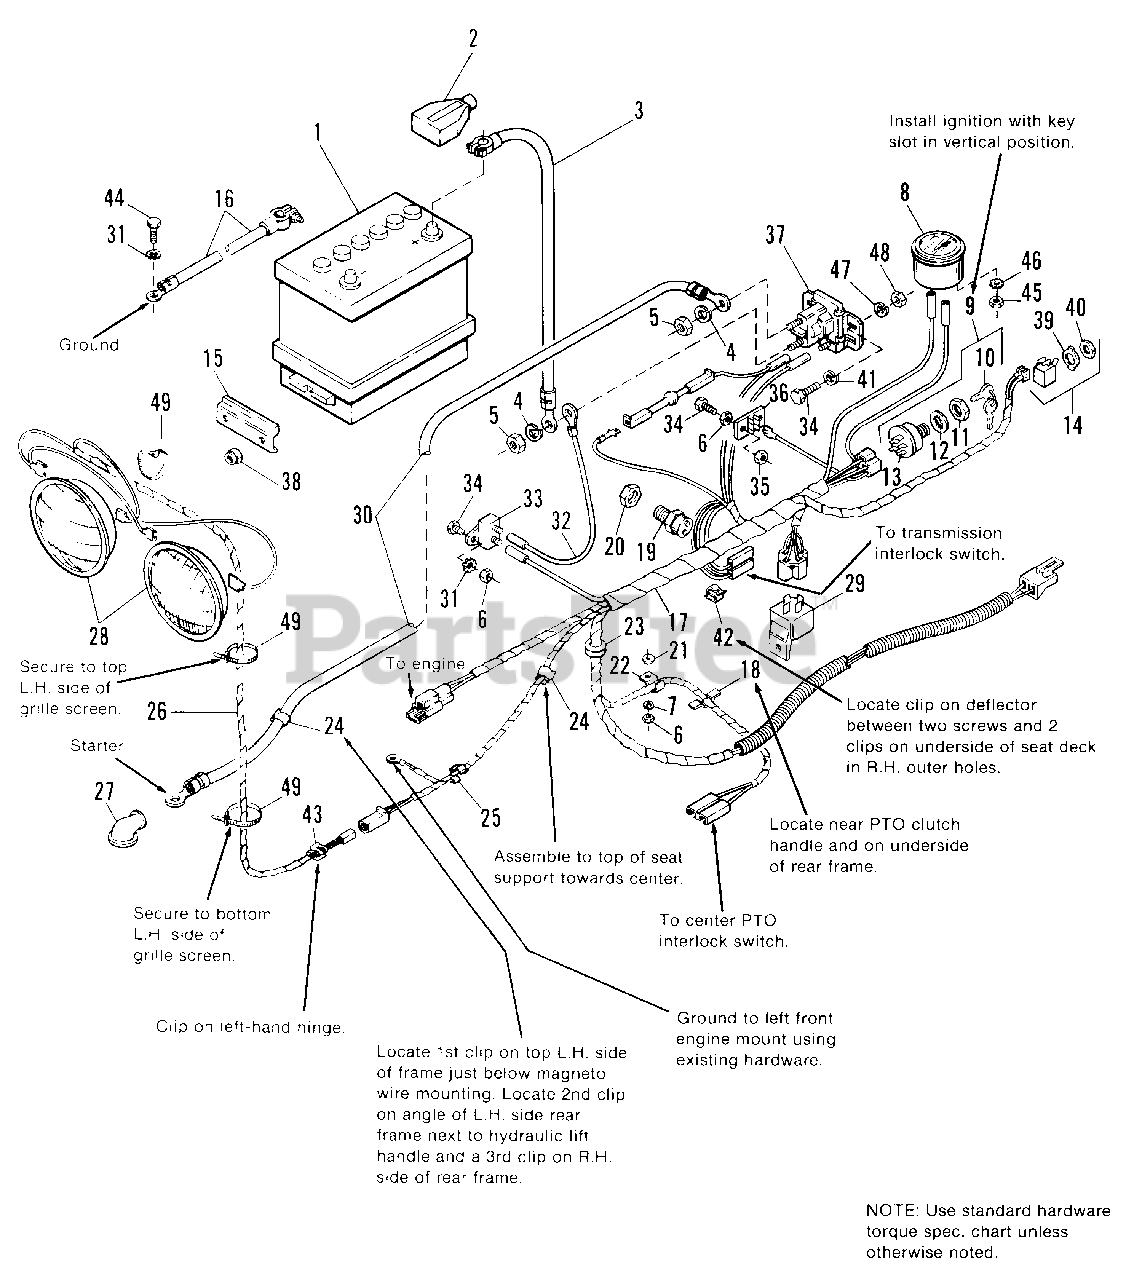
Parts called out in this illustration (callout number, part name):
1	BATTERY (Includes decal)
2	INSULATING CABLE BOOT
3	CABLE (Battery to Solenoid)
4	LOCKWASHER, 5/16
5	NUT, Hex, 5/24
6	NUT, Hex, Full, 1/4-20
7	LOCKWASHER, 1/4
9	SWITH & KEY ASSY., Ignition (Incl. Ref. Nos. 10-13)
10	KEY SET (2)
11	NUT, Special
12	LOCKWASHER, Int., 5/8
14	SWITCH, Toggle
16	CABLE (Battery to Ground)
17	HARNESS ASSY.
18	CLIP, Wire
19	SWITCH, Interlock
21	WASHER, Plain
22	CLIP, Cable
24	CLIP, Tinnerman
25	CLIP, Tinnerman
27	COVER, Terminal
28	LAMP, Sealed Beam, G.E. #4411-1
29	RELAY, Electric
30	CABLE (Solenoid to Starter)
31	LOCKWASHER, Ext. Tooth, 1/4 (Zinc Pltd.)
33	BREAKER, Circuit
34	CAPSCREW, Hex Hd., 1/4-20 x 5/8
35	LOCKNUT, Hex, 1/4-20
36	BOARD, Terminal
37	SOLENOID, Starter
38	LOCKNUT, Hex, Esna, 5/16-18
40	NUT, Switch
41	WASHER, Special, 1/4 (Zinc Pltd.)
42	CLIP, Wire
43	CLIP, Speed Cable
44	CAPSCREW, Hex Hd., 1/4-20 x 1/2 (Zinc Pltd.)
45	NUT, Hex, #10-32
46	LOCKWASHER, Ext. Tooth
47	LOCKWASHER, 1/4 (Zinc Pltd.)
48	NUT, Hex, 1/4-20 (Zinc Pltd.)
